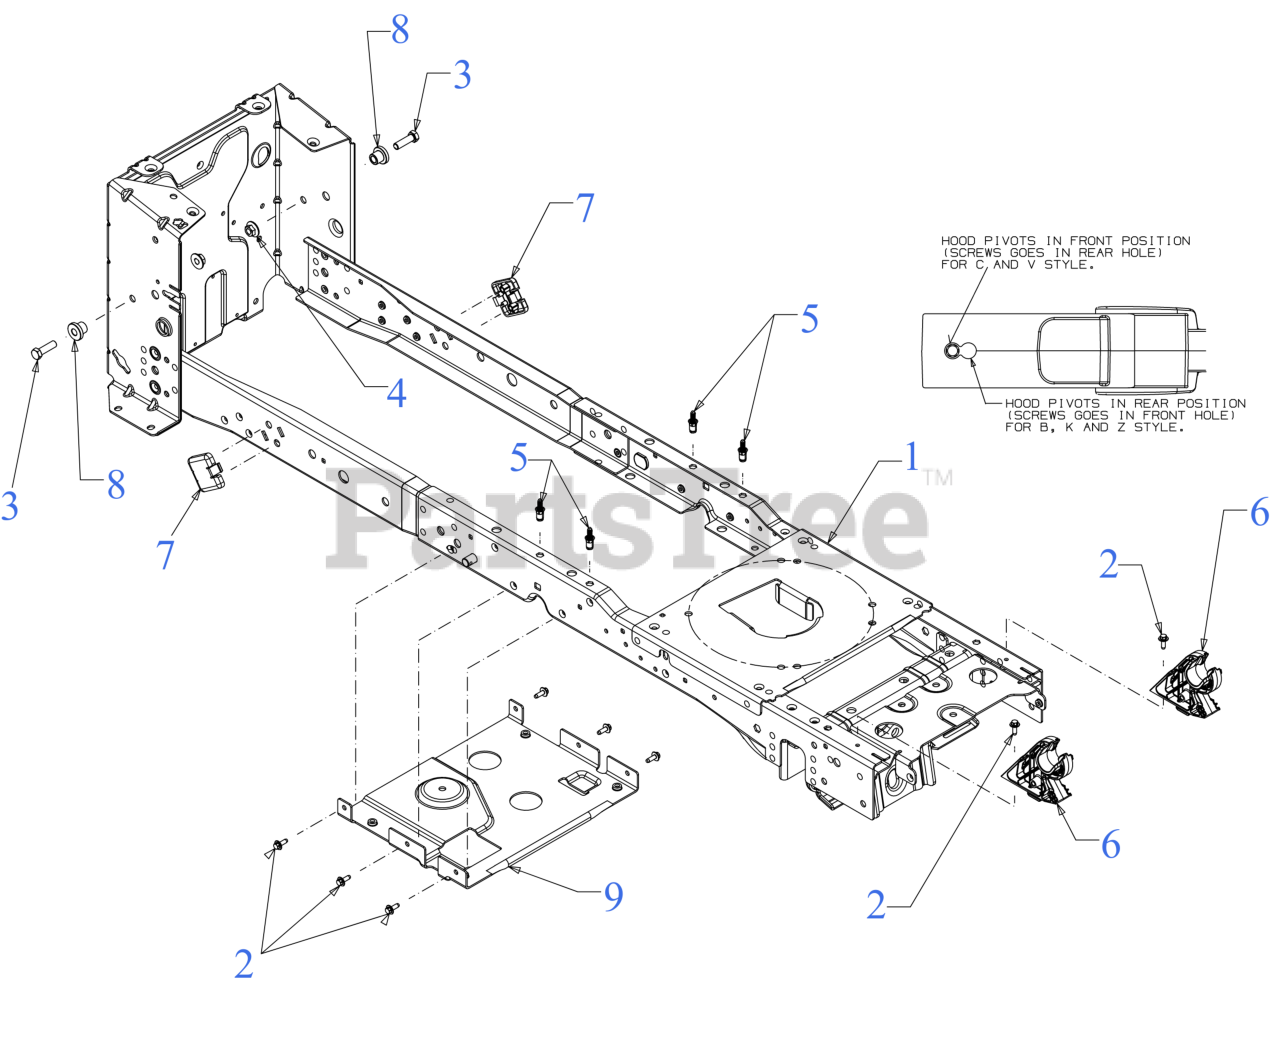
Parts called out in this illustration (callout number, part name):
1	FRAME ASSEMBLY
2	SCREW M6-1 x .625
3	SCREW 3/8-16 x 1.25 GR5
4	FLANGE LOCK NUT
5	RIVET-HEX STUD 1/4-20 FRM
6	HOOD PIVOT BRACKET
7	LIFT ROD WEAR PAD
8	SHOULDER SPACER
